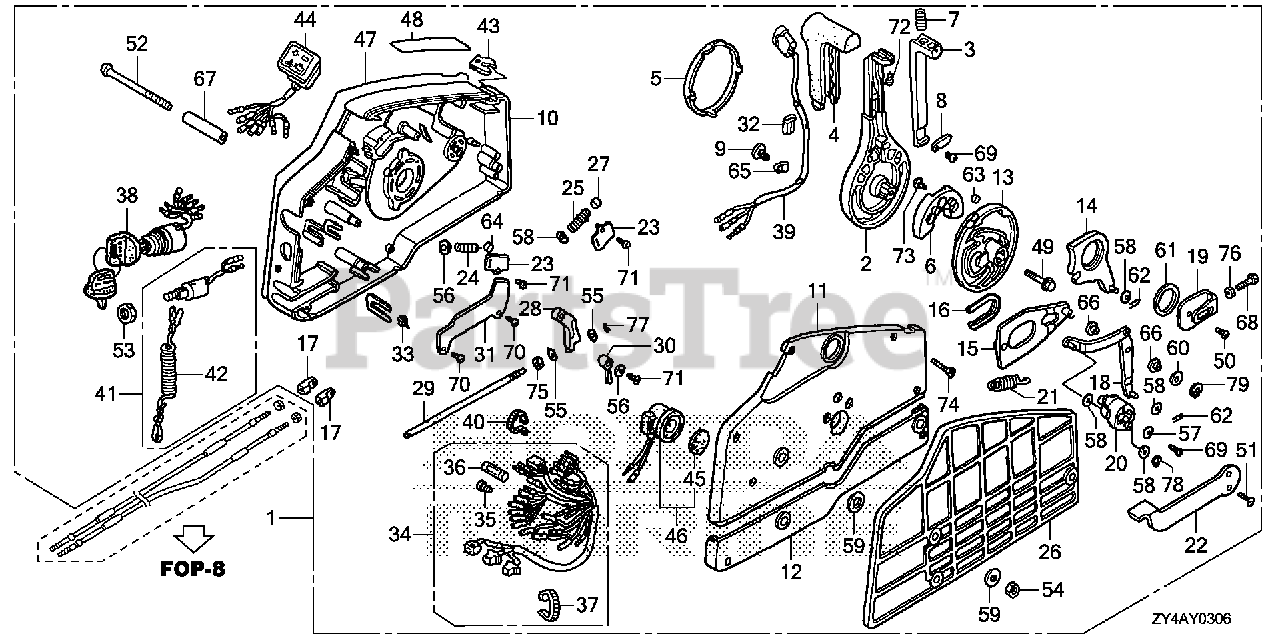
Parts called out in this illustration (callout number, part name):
1	BOX ASSY., REMOTE CONTROL (NHK MEC)
1	BOX ASSY., REMOTE CONTROL (TROLLING CONTROL)(NHK MEC)
2	HANDLE, REMOTE CONTROL
3	LEVER, HANDLE LOCK
4	GRIP, REMOTE CONTROL HANDLE
5	CAP, HANDLE
6	BLOCK, NEUTRAL LOCK
7	SPRING, REMOTE CONTROL HANDLE
8	PLATE, LEVER SETTING
9	CLAMP, HARNESS
10	HOUSING, REMOTE CONTROL BOX (A)
11	HOUSING, REMOTE CONTROL BOX (B)
12	HOUSING, REMOTE CONTROL BOX (C)
13	WHEEL, CONTROL
14	ARM, SHIFT LINK
15	PLATE, SLIDING
16	COLLAR, SLIDING PLATE
17	PIVOT, SHIFT
18	ARM, LINK JOINT
19	BRACKET, LINK JOINT
20	WHEEL, ACCELERATOR
21	SPRING, ACCELERATOR WHEEL
22	LEVER, IDLE
23	PLATE, SPRING SETTING
24	SPRING, SHIFT CLICK
25	SPRING, CHOKE RETURN
26	SPACER, REMOTE CONTROL BOX
27	SPACER, CLICK SPRING
28	BLOCK, THROTTLE FRICTION
29	BOLT, FRICTION
30	SPACER, NEUTRAL SWITCH
31	CLAMP, POWER TILT CORD
32	PIPE, HARNESS GUIDE
33	SPACER, CABLE CLAMP
34	CABLE ASSY., REMOTE CONTROL (B)
35	PLUG, CONNECTOR (INNER)
36	PLUG, CONNECTOR (OUTER)
37	TIE, CABLE (2.4X92) (NATURAL)
38	SWITCH ASSY., COMBINATION
39	SWITCH ASSY., POWER TRIM-TILT
40	BAND (BLACK 3.5X140)
41	SWITCH ASSY., EMERGENCY STOP
42	WIRE, EMERGENCY
43	CLIP, EMERGENCY LOCK
44	LAMP ASSY., INDICATION
45	PLATE, TURN SIGNAL BUZZER
46	BUZZER, WARNING
47	PLATE, REMOTE CONTROL (COUTION COLOR=RED & YELLOW)
48	MARK, FAST IDLE
49	BOLT, FLANGE (8X35)
50	SCREW, PAN (6X10)
51	SCREW, FLAT (5X12)
52	SCREW (6X95)
53	NUT, HEX. (16MM)
54	NUT, HEX. (6MM)
55	WASHER, PLAIN (4MM)
56	WASHER, PLAIN (5MM)
57	WASHER, PLAIN (5MM)
58	WASHER, PLAIN (6MM)
59	WASHER (6MM)
60	WASHER, PLAIN (8MM)
61	WASHER (28MM)
62	PIN, LOCK (6MM)
63	PIN (6X6)
64	ROLLER, CLICK
65	CLIP, WIRE HARNESS (6.3MM)
66	COLLAR, LINK JOINT
67	COLLAR, DISTANCE (6X10X43.5)
68	BOLT, HEX. (5X16)
69	SCREW, PAN (5X10)
70	SCREW, TAPPING (5X8)
71	SCREW, TAPPING (5X10)
72	SCREW, TAPPING (5X12)
73	SCREW, TAPPING (6X16)
74	SCREW, TAPPING (5X25)
75	NUT, HEX. (6MM)
76	NUT, HEX. (5MM)
77	E-RING (3MM)
78	E-RING (4MM)
79	E-RING (7MM)
